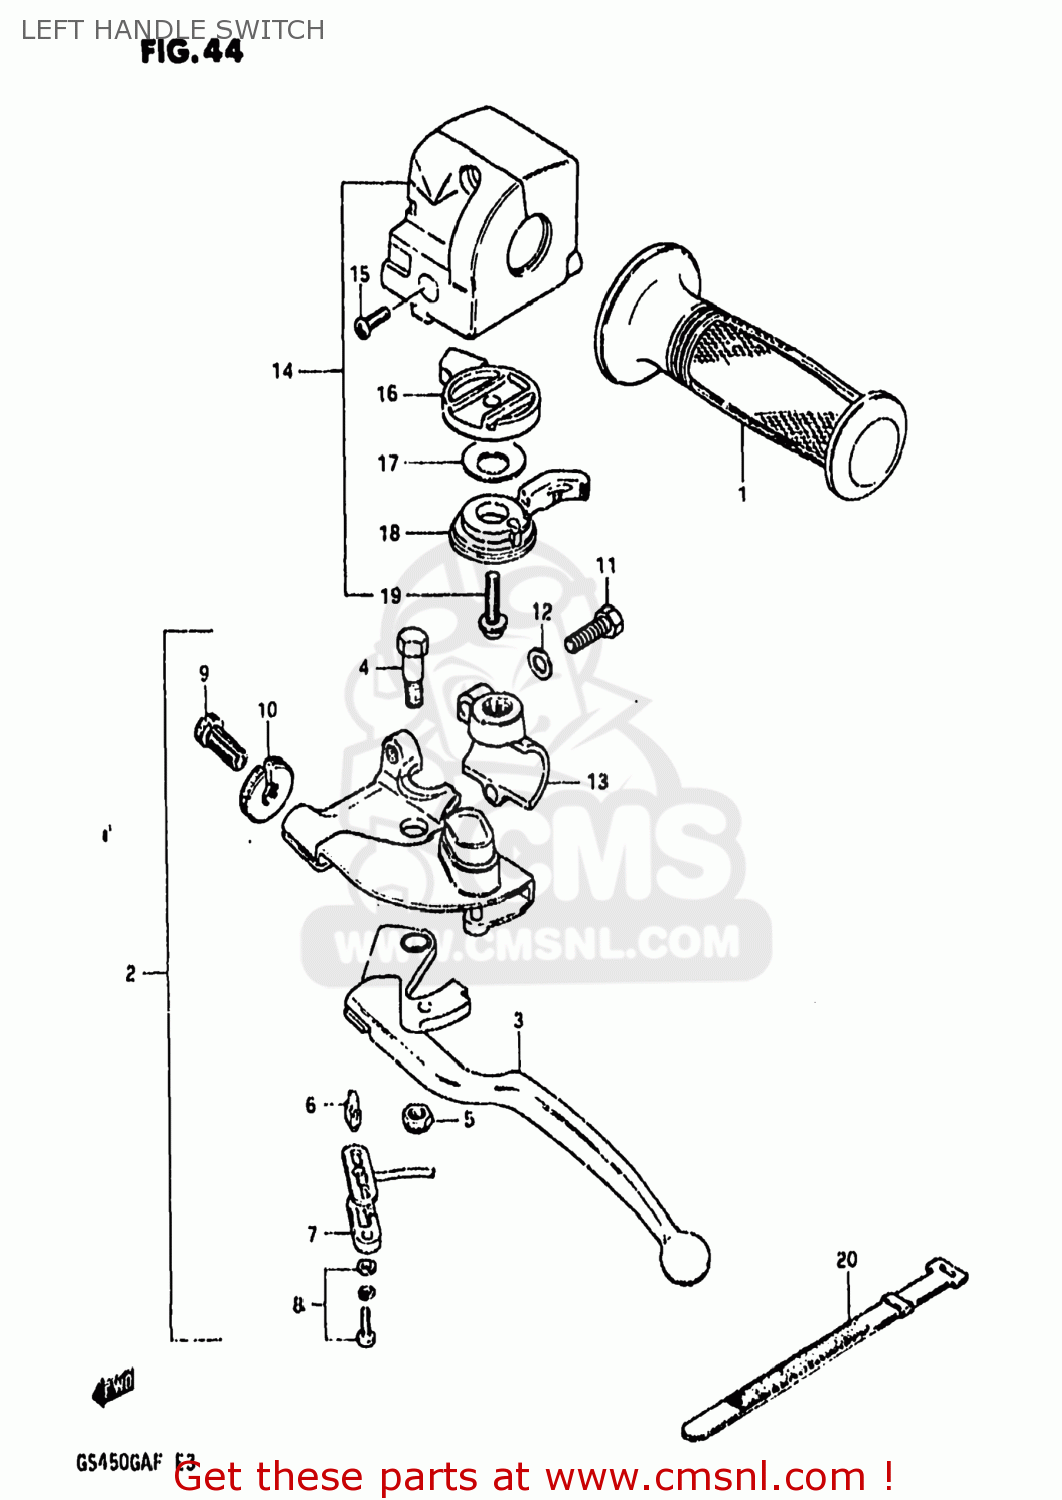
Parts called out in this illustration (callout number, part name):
1	GRIP
2	LEVER ASSEMBLY,PARKING BRAKE
3	LEVER,PARKING
4	BOLT,LEVER
5	NUT
6	CONTACT,SWITCH
7	COVER,FR BK TERMINAL BASE
8	SCREW
9	ADJUSTER,CABLE
10	NUT,CABLE ADJUSTER LOCK
11	BOLT
12	WASHER
13	HOLDER
14	SWITCH ASSEMBLY,HANDLE,LEFT
15	SCREW
16	BODY,STARTER LEVER
17	WASHER,ADJUSTER
18	LEVER,STARTER
19	SCREW,CHOKE LE
20	CLAMP(L:120)
